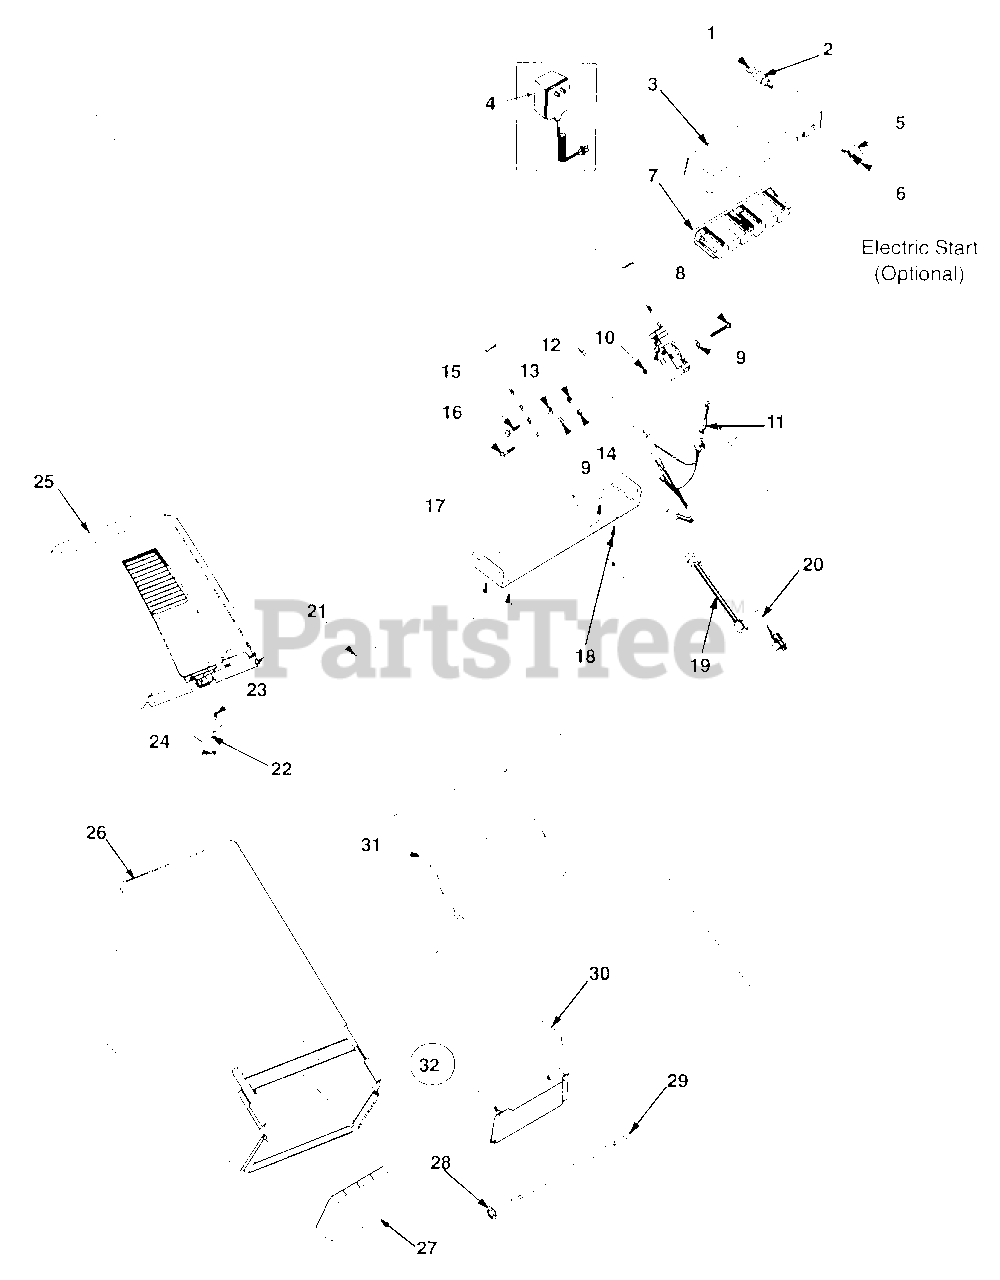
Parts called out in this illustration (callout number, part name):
1	Ignition Key
2	Key Switch
3	Battery Tray
4	Battery Charger
5	Fuse 7.5 Amp
6	Fuse Holder
7	Battery 12V
8	Hex Screw: 1/4-20:2.0
9	Bell Washer .265 x .75 x .062
10	Special Hex Nut 5/16-18
11	Plug
12	Nut 5/16-18
13	Bell Wash .340 ID x .872 OD
14	Hex Nut 1/4-20
15	Carriage Bolt 5/16-18 x 1
16	Carriage Screw
19	Harness Extension
20	Harness
23	Hex Screw 1/4 -20 x .5
24	Hex Nylon L-Nut 1/4-20
25	Hardtop Cover w/o Logo: Econo: Blk.
26	Grass Bag: Soft Top w/ Logo
27	Mulcher Plug
28	Nut: Spd. .3125 ID
30	Side Discharge Adapter
